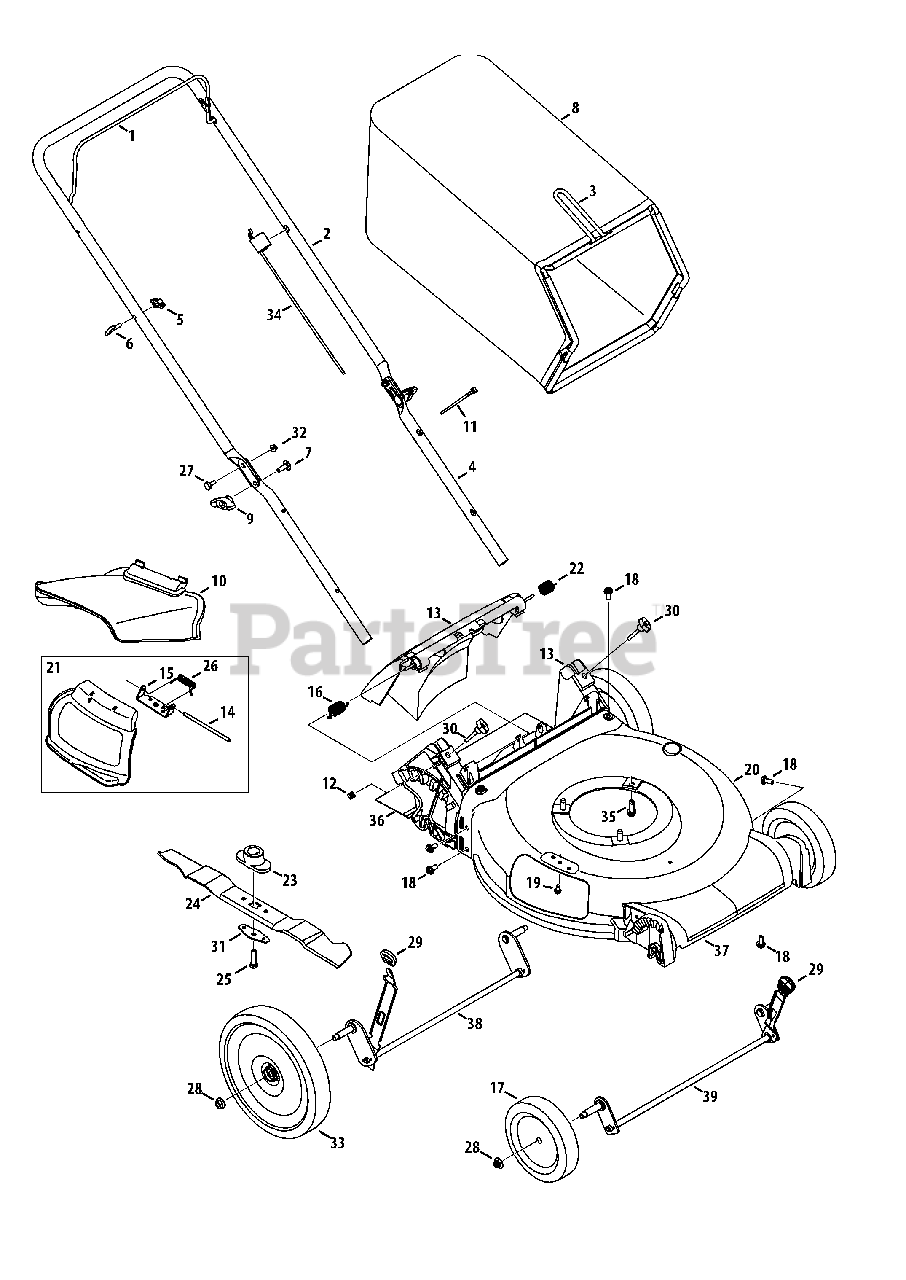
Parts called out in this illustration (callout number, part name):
1	Blade Control, Standard
2	Upper Handle
3	Grass Catcher Frame
4	Lower Handle
5	Wing Nut
6	Rope Guide
7	Carriage Screw ,5/16-18
8	Grass Bag
9	Wing Knob
10	Side Chute
11	Cable Tie
12	Nut, Sq., 1/4-20
13	Rear Discharge Door Assembly
14	Hinge Pin
15	Chute Deflector Bracket
16	Torsion Spring - RH
17	Font Wheel Gray
18	Screw, 5/16-14 x .750
19	Screw, 1/4-20 x .500
20	Deck , 21"
21	Hinged Mulch Plug Assembly
22	Torsion Spring - LH
23	Blade Adapter, 25mm x 1.19
24	Mulching Blade
25	Screw , 3/8-24 x 1.50
26	Torsion Spring
27	Sldr. Screw, .375 x .126 x 1/4-20
28	Flange Lock Nut, 3/8-16
29	Adjustment Lever Knob
30	Wing Nut, Black
31	Blade Bell Support
32	Nut, Flange Lock, 1/4-20
33	Rear Wheel Gray
34	Control Cable, 37.58"
35	TT Sems Screw, 3/8-16 x 1.0
36	Trail shield
37	Front Cover
38	Rear Axle Assembly
39	Front Axle Assembly
